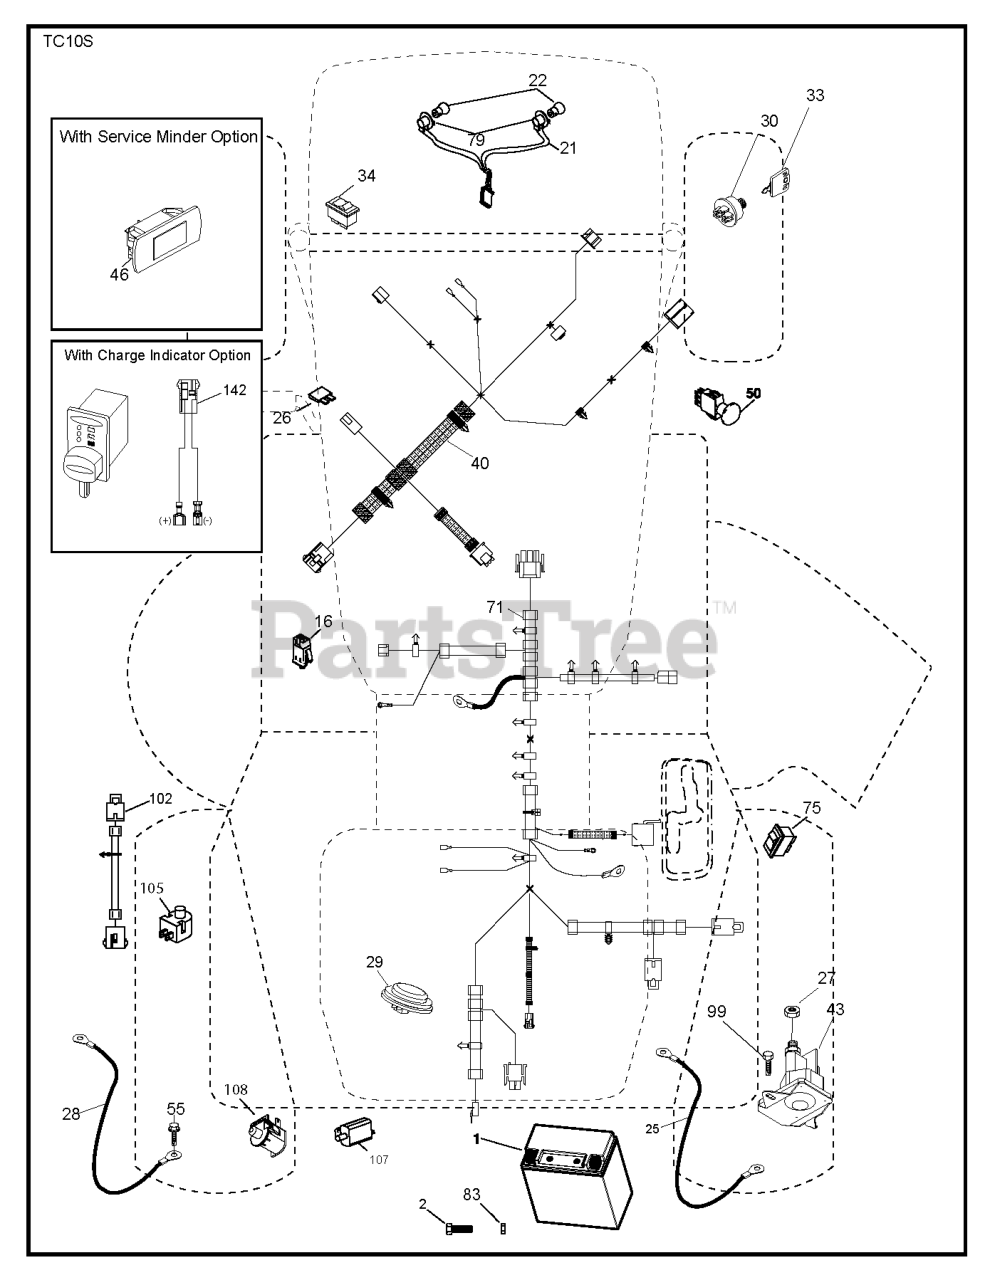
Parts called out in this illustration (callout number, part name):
1	BATTERY BATTERY 14AH 12V LEOC
2	SCREW.HEX.HEAD.CAP.M6 X1.12W
16	SWITCH INTERLOOK PUSH-IN
21	HARNESS.LIGHT W/4152J BULBS
25	CABLE CABLE.BLACK.20.8AWG.M6.C
26	FUSE 20AMP
27	NUT
28	SUPPORT SUPPORT.SSST.REAR.FRAM
29	SWITCH.SEAT.DELTA.OPC.
30	SWITCH.IGN.DELTA.W.LGH.ROS
33	KEY.CHAIN.BLISTER.PACK.GEN.INT
40	HARNESS.DASH.ELECT.SRD.BAT.CHR
43	SOLENOID.W/BRASS.PLUNGER
46	RP.GUAGE.SRVCMNDR.HRMTR.
50	RP.PTO.SWITCH.8 TERMINAL.BLACK
55	SCREW 5/16"
71	HARNESS.CH.TCRD.HYD.TWIN.ELD.
75	SWITCH.BAG.DUMP
79	BULB HOLDER ASM.
83	NUT NUT SQUARE
99	SCREW
102	HARNESS ASSY
105	REVERSE SWITCH
107	.WITCH.FULL BAGGER.INDICATOR
108	SWITCH.SNAPMOUNT.NC
142	RP HARNESS.JUMPER.CTEK
